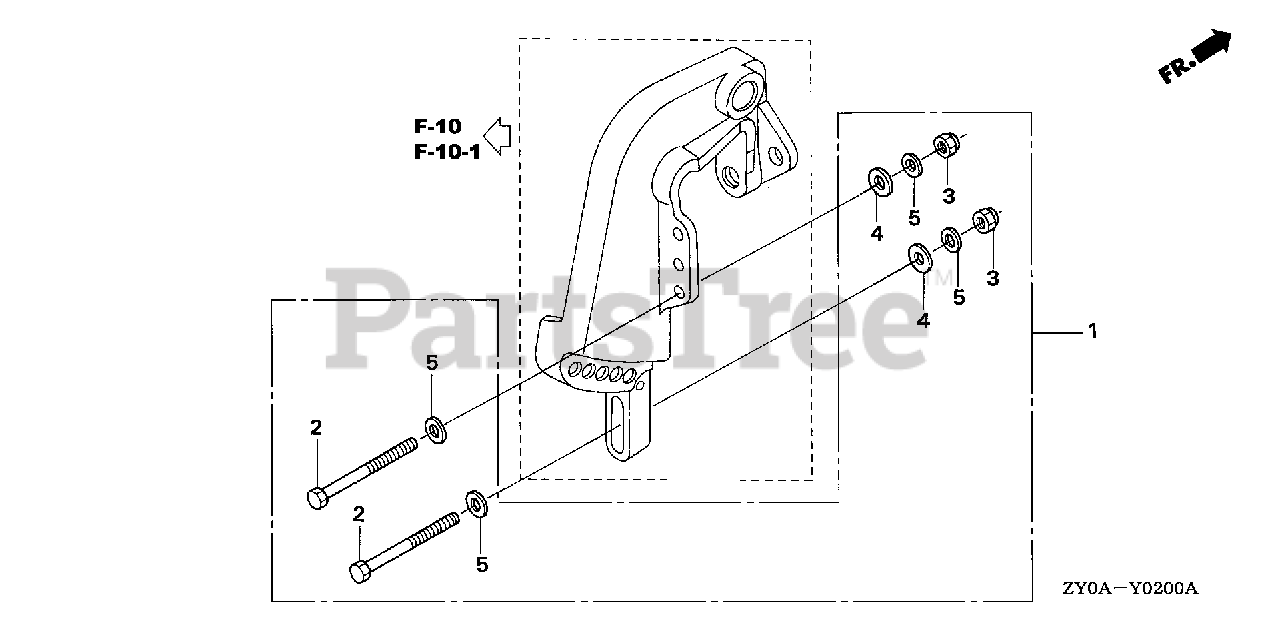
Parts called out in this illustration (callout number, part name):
1	INSTALLATION KIT, OUTBOARD
2	BOLT, HEX. (10X100)
3	NUT, SELF-LOCK (10MM)
4	WASHER, PLAIN (10MM)
5	WASHER, PLAIN (10MM)
